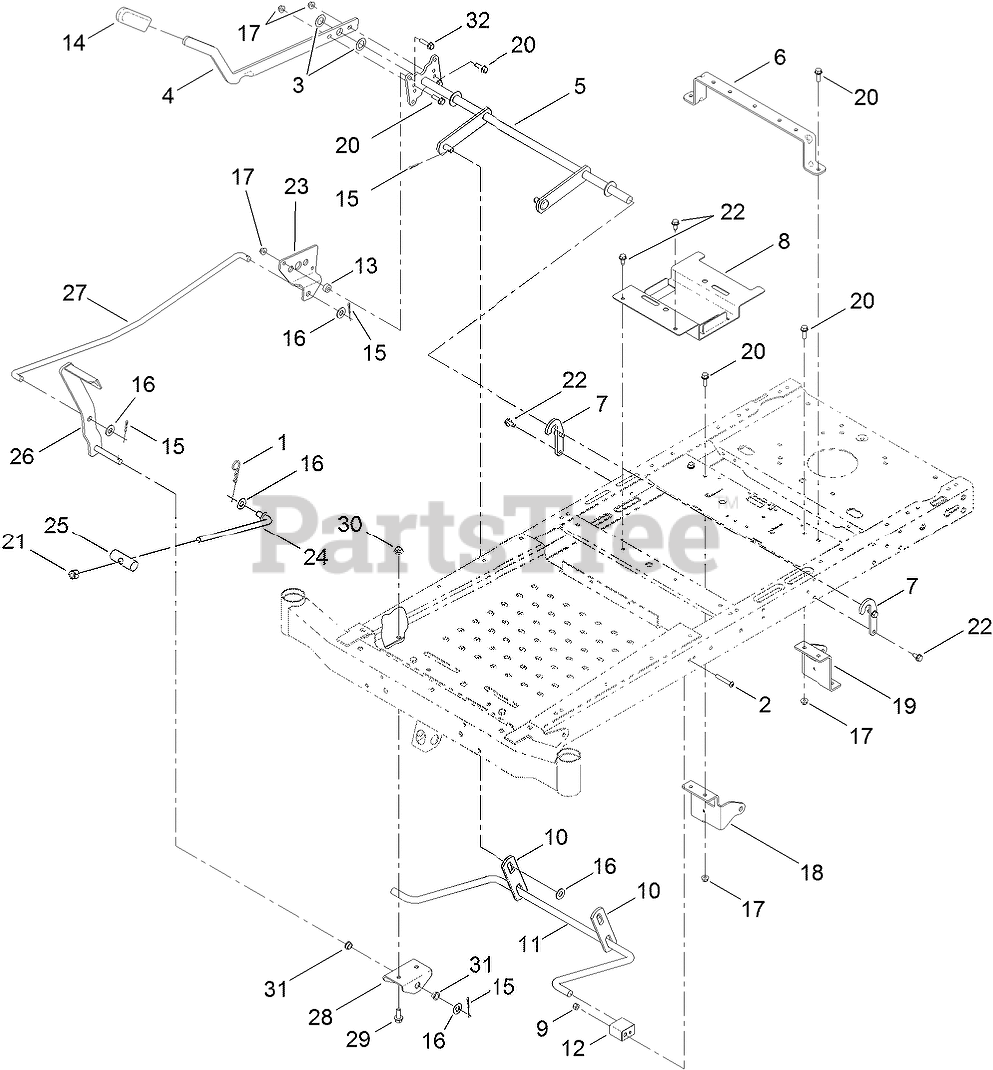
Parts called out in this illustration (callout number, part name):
1	PIN-COTTER
2	SCREW-HSBH
3	WASHER-THRUST
4	LEVER-LIFT
5	LIFT-DECK, WIDE
6	BRACE-SEAT, REAR
7	BRACKET-LIFT
8	BRACKET-BATTERY
9	NUT-LOCK, NI
10	LINK-LIFT
11	ARM-LIFT, REAR (WIDE)
12	BLOCK-PIVOT
13	SPACER
14	GRIP-LEVER
15	PIN-COTTER
16	WASHER-FLAT
17	NUT-HF, NI
18	MOUNT-HYDRO, FRONT (RH)
19	MOUNT-HYDRO, FRONT (LH)
20	SCREW-HHF
21	NUT-HEX
22	SCREW-HWHTF
23	PLATE-FOOTLIFT
24	ROD-TRUNION
25	PIN-PIVOT
27	ROD-FOOTLIFT
28	BRACKET-FOOTLIFT
29	SCREW-HHF
30	NUT-HF, NI
31	BUSHING-FLANGE
32	SCREW-HHF
